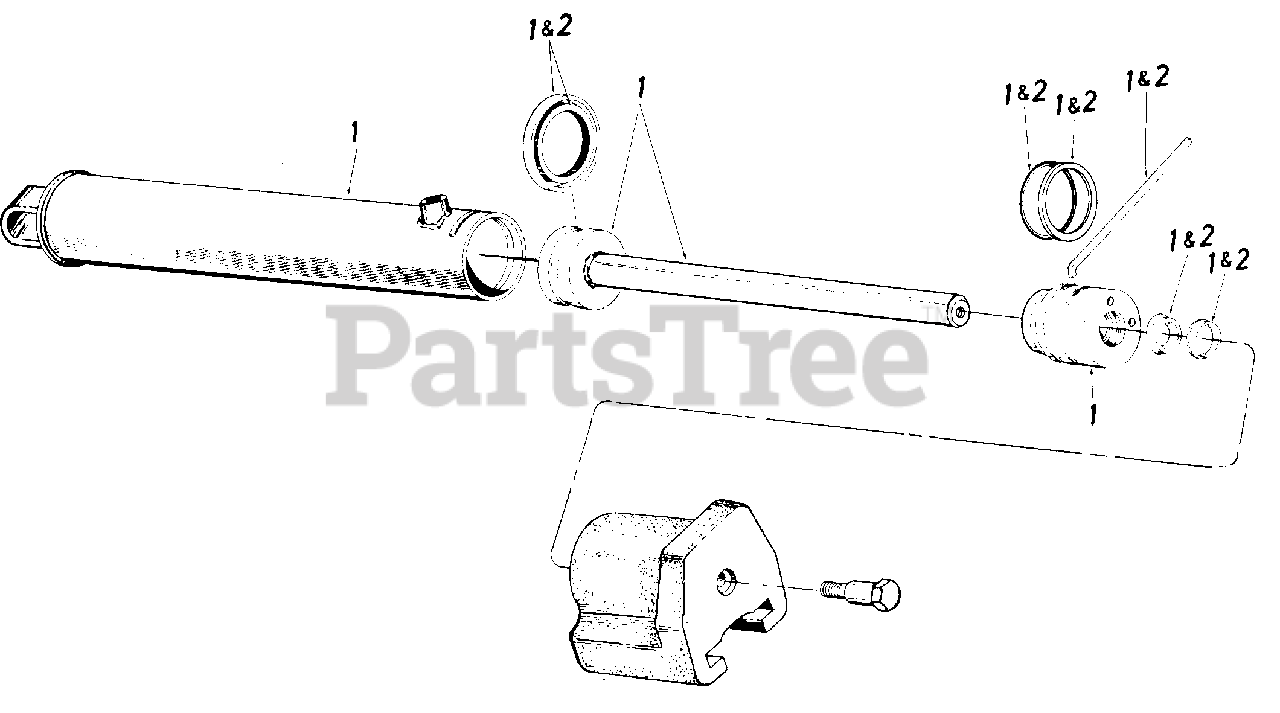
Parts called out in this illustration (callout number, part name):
1	Cylinder Ass'y. Comp.
1	Cyl inder Ass'y. Comp
2	3-1/2" Cyl. Kit "O"-RingSet
2	4" Cyl. Kit "O"-Ring Set
